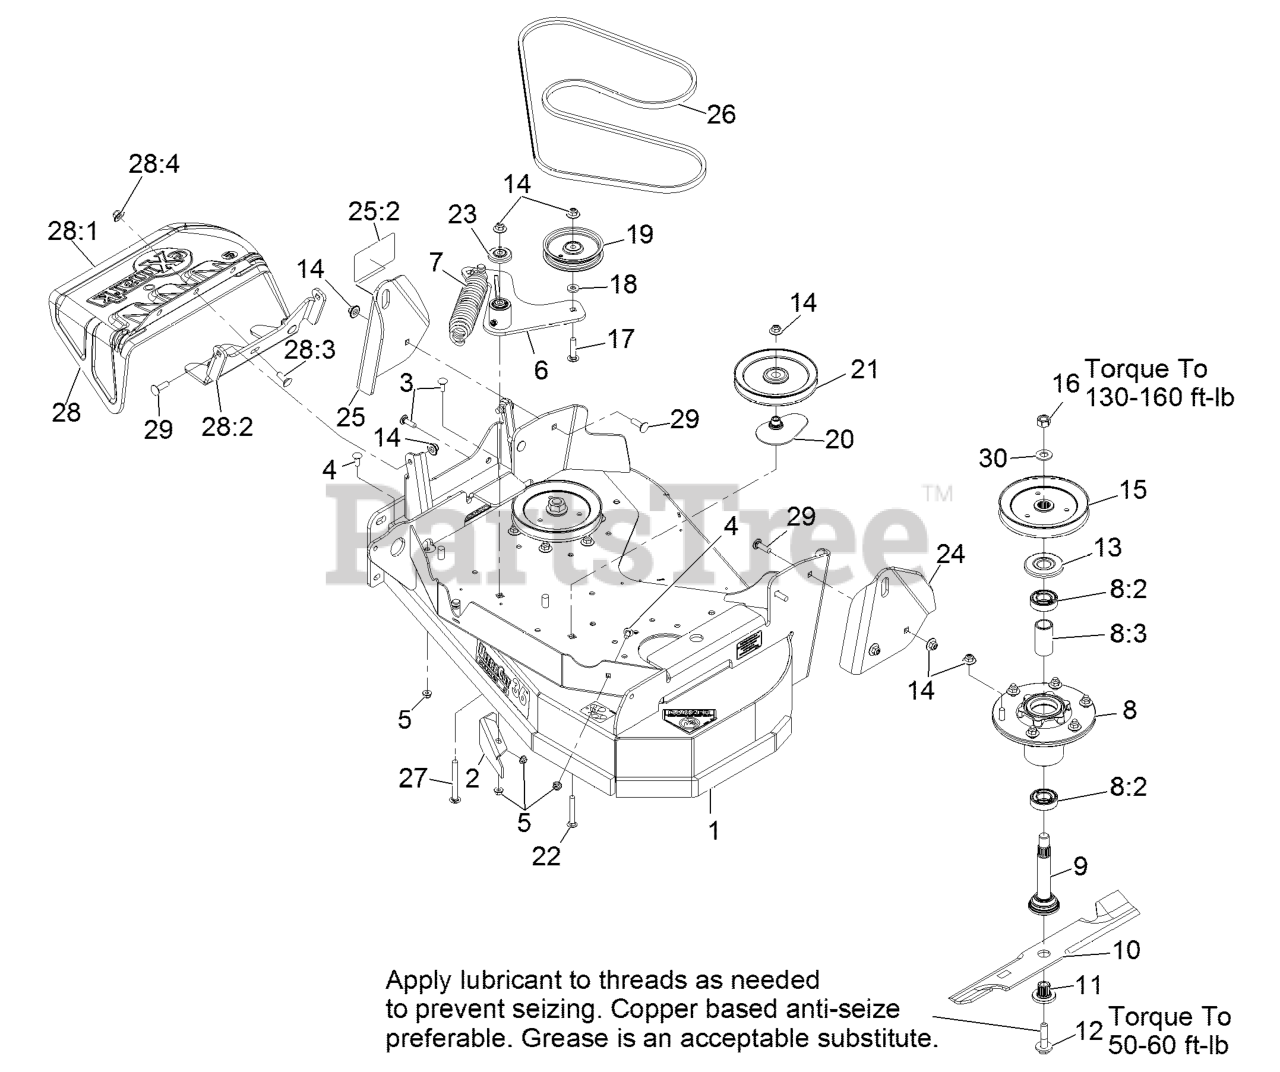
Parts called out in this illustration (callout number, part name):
1	DECK ASM - 36
2	BAFFLE-DOGLEG
3	SCREW-CARR
4	SCREW-CARR
5	NUT-HF, NI
6	IDLER ARM ASM -
7	SPRING-EXTENSION
8	ASM-CUTTER HSG WITH BEARINGS
8:2	BEARING-BALL
8:3	SPACER-BEARING
9	ASM-SPINDLE AND SEAL
11	BUSHING,SPLINED
12	SCREW,SEMS 1/2-20 X 2.19
13	GUARD,BEARING TOP .989
14	Nut-Nyloc 3/8-16 Flg
15	SHEAVE,BLADE DRIVE 6.50
16	NUT-HEX
17	SCREW-CARR
19	PULLEY-IDLER
20	SPACER-PULLEY
21	PULLEY-IDLER
22	SCREW-CARR
23	GUARD-TOP
24	PUSH-TOWER,LH 36
25	PUSH TOWER-RH 36, W/DECAL
25:2	DECAL-WARNING, DISCHARGE
26	BELT-V
27	BOLT-SHOULDER, CARRIAGE 3/8-16 X 3 1/2
28	CHUTE - DISCHARGE ASM
28:1	CHUTE,DISCHARGE
28:2	BRACKET-CHUTE, DISCHARGE
28:3	SCREW-CARR
28:4	Nut-Nyloc 3/8-16 Flg
29	Bolt-Carriage 3/8-16 X 1 1/4
